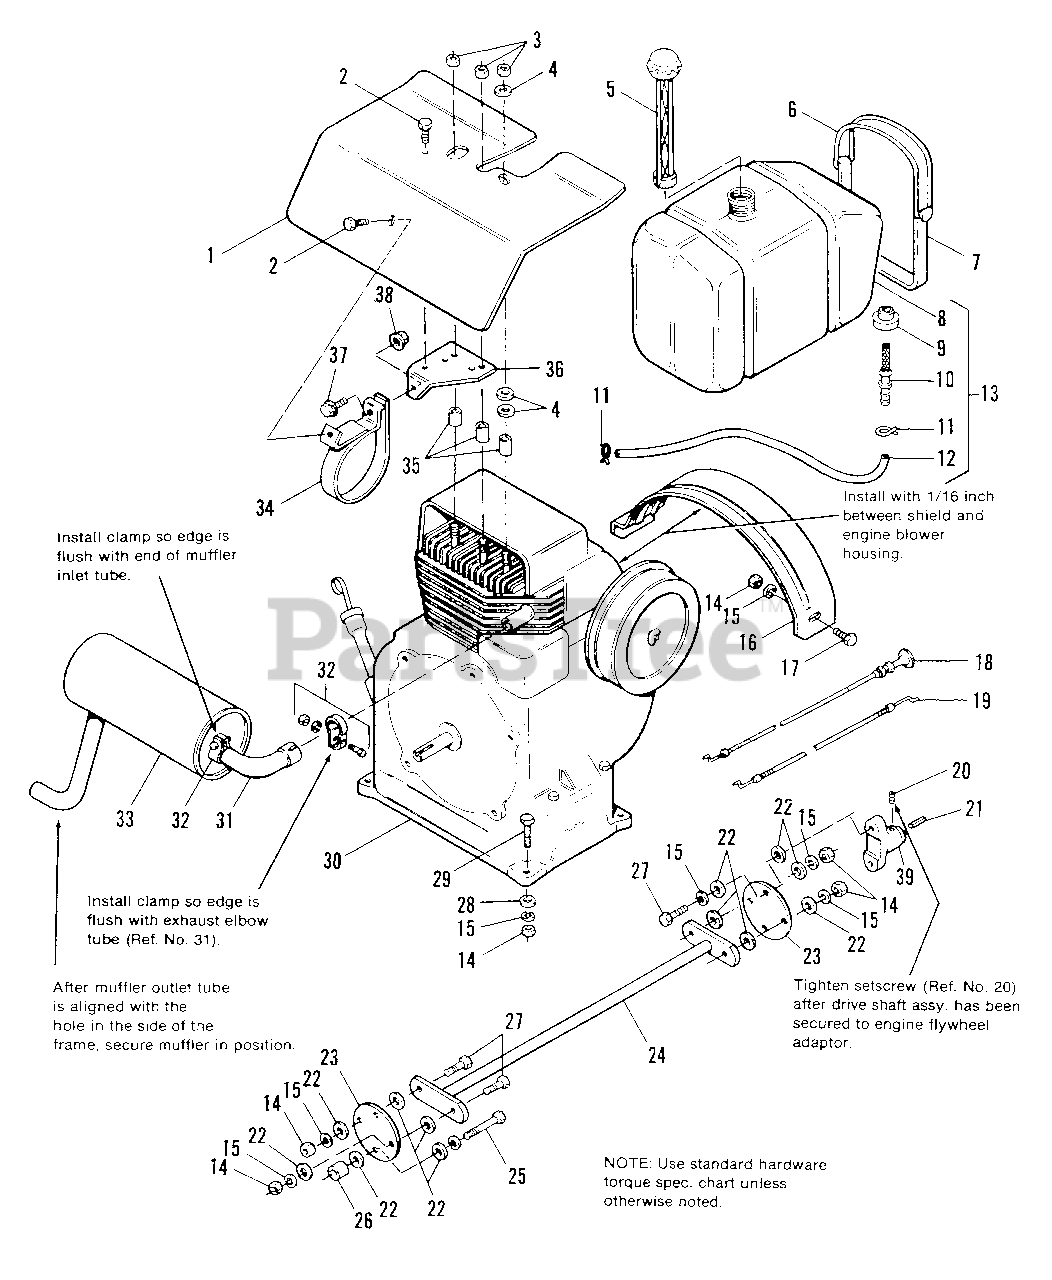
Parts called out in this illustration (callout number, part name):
1	SHIELD, Heat
2	SCREW, Hex, Taptite, 1/4-20 x 1/2
3	LOCKNUT, Hex, Jam, 3/8-16
5	CAP, Fuel Tank
6	STRAP, Fuel Tank
7	STRAP, Tank
11	CLAMP, Hose
13	TANK ASSY., Fuel
14	NUT, Hex, Full, 3/8-16
15	LOCKWASHER, 3/8
17	CAPSCREW, Hex Hd., 3/8-16 x 3/4
18	CONTROL, Choke
19	CONTROL, Throttle
20	SETSCREW, 3/8-24 x 3/8
21	KEY, Drive Shaft
22	WASHER, Special
24	SHAFT ASSY., Drive
25	CAPSCREW, Hex Hd., 3/8-16 x 2-1/4
27	CAPSCREW, Hex Hd., 3/8-16 x 1-1/4
28	WASHER, Plain, 3/8
29	CAPSCREW, Hex Hd., 3/8-16x 1-1/2
30	ENGINE, 12 HP Kohler
31	ELBOW, Exhaust
32	CLAMP, Muffler
33	MUFFLER, Exhaust
34	STRAP ASSY., Muffler
36	SUPPORT, Muffler
37	CAPSCREW, Hex, Whiz, Flange, 5/16-18 x 1-1/2
38	NUT, Hex, Flange, 5/16-18
39	FLANGE, Drive Shaft
